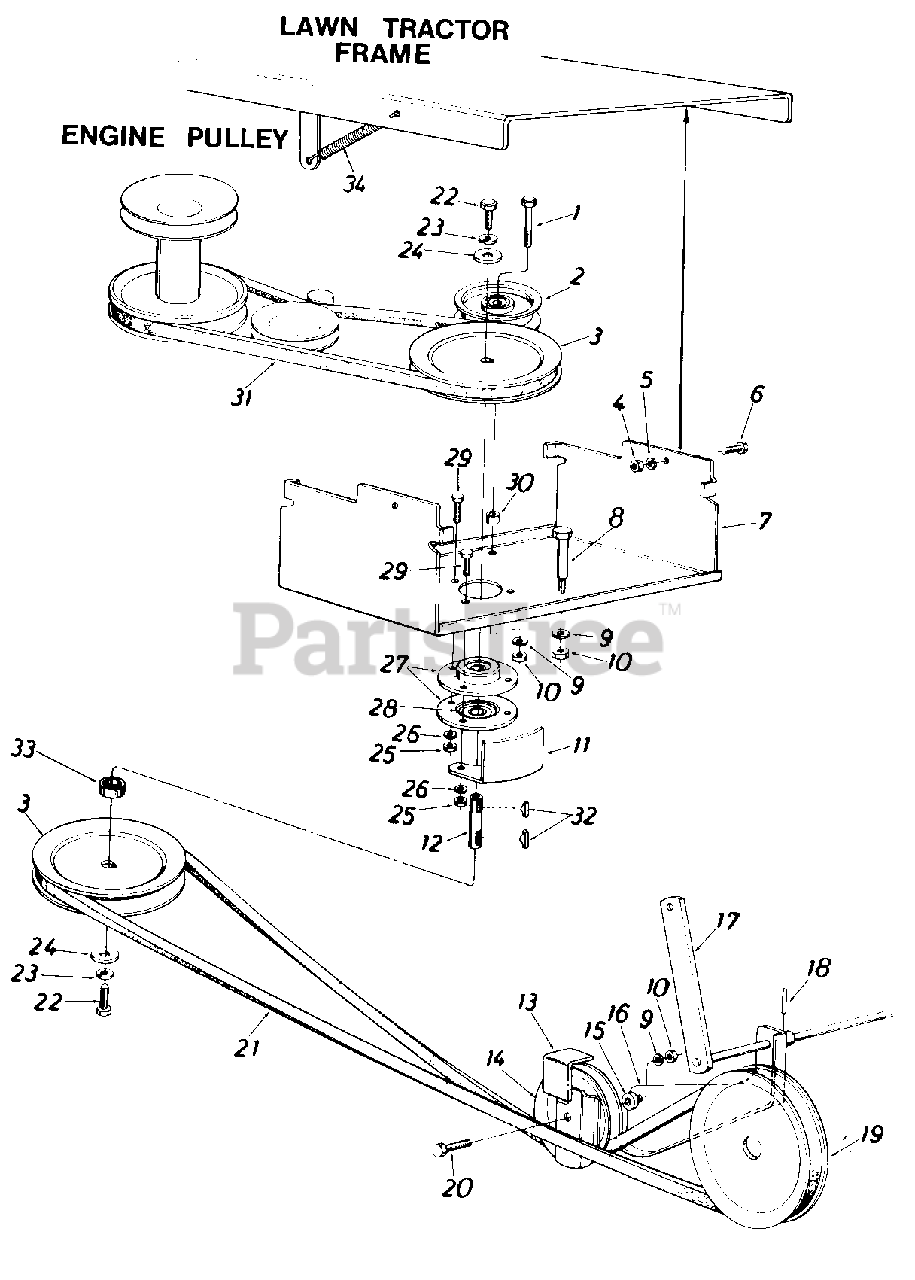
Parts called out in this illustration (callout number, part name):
1	Hex Bolt 3/8-16 x 2.00" Lg.
2	Fl.-ldler w/Flanges 3-3/4" O.D.
3	5/8" "V"-Pulley.790" I.D. x .650" O.D.
4	Hex Nut 3/8-24 Thd.*
5	L.-Wash. 3/8" I.D. Heavy Duty
6	Hex Bolt 3/8-24 x .88" 4.*
7	Carriage Bracket
8	Shoulder Bolt .498" Dia.
9	L.-Wash. 3/8" I.D.*
10	Hex Nut 3/8-16 Thd. Lg.
11	Belt Guard
12	Shaft .787" Dia. x 3.21" Lg.
13	Belt Separator Plate
14	Fl.-ldler w/Flanges 3.25"
15	Fl.-Wash. .406" I.D. x 1.25"
18	Spring Pin Roll 3/16" Dia.
19	5/8" V-pulley 1.50" I.D. x 6.50" O.D.
20	Hex Bolt 3/8-16 x 1.75" Lg.
21	V-Belt
22	Hex Bolt 5/16-18 x .88" Lg. Spec.
23	L.-Wash 5/16" I.D.*
24	Fl.-Wash. .344" I.D. x 1.125"
25	Hex Nut 5/16-18 Thd. Lg.
26	L.-Wash. 5/16" I.D.*
27	Bearing Housing 1.85" I.D.
28	Ball Bearing 1.85" O.D.
29	Hex Sems Bolt 5/16-18 x .75"
30	Spacer
31	Belt 1/2" Wide x 52" Long
32	Hi-Pro Key 3/16" x 5/8"
33	Spacer.66" I.D. x 1.0" O.D.
34	Extension Spring
